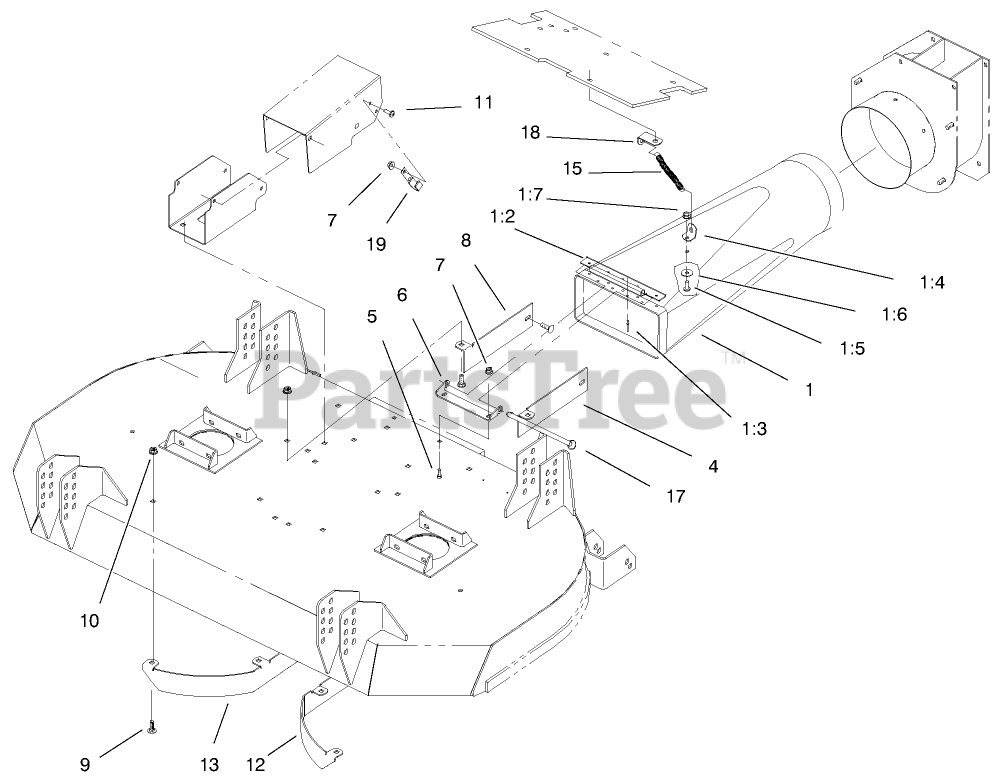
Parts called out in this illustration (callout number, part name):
1	ASM - PLENUM
1:2	BRACKET - PLENUM
1:3	RIVET-POP
1:4	BRACKET-SPRING
1:5	SCREW-PPH
1:6	WASHER-FLAT
1:7	NUT-HHF
4	Bracket-Discharge
5	SCREW-CARR
6	BRACKET - HINGE
7	NUT-HHF
8	Bracket-Discharge
9	SCREW-CARR
10	NUT-HF
11	SCREW-PPH
12	Baffle-LH
13	Baffle-RH
15	SPRING - EXTENSION
17	PIN - LOCKING
18	BRACKET - SPRING
19	CLIP - CABLE
